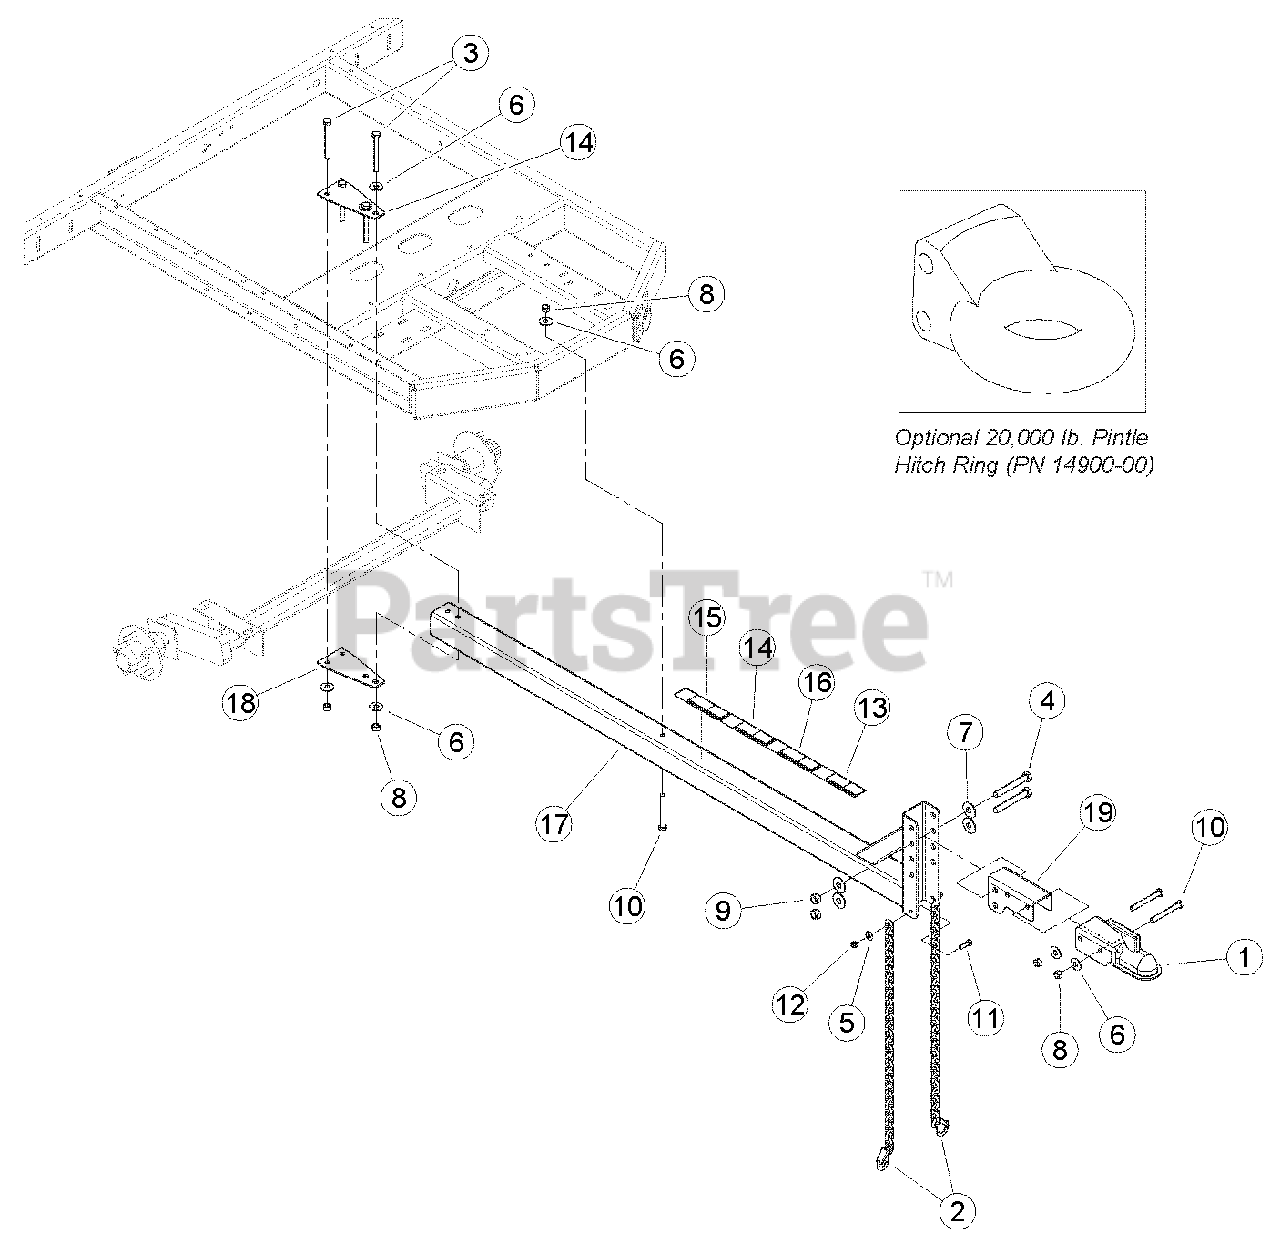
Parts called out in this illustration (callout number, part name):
1	COUPLER, 2 IN
2	CHAIN, SAFETY, 5000 LB W/LATCH
3	BOLT, 1/2 X 4-1/2 HEX HD GR5
4	BOLT, 5/8 X 4-1/2 HEX HD GR5
5	WASHER, 3/8 FLAT ZP
6	WASHER, 1/2 FLAT ZP
7	WASHER, 5/8" FLAT ZP-37PCS/LB
8	NUT, 1/2 CENTERLOCK GRB ZP
9	NUT, 5/8 CENTERLOCK
10	BOLT 1/2 X 4 HEX HD GR5 ZP
11	BOLT, 3/8 X 1-1/4 HEX HD GR5 ZP
12	NUT, 3/8 NYLOCK
13	DECAL, SAFETY CHAINS
14	DECAL, TRAILER ELECTRICAL
15	DECAL, CHECK WHEELS
16	DECAL, SAFE COUPLING
17	WELDMENT, HITCH POLE
18	PLATE, AXLE SAFETY
19	MOUNT, COUPLER
